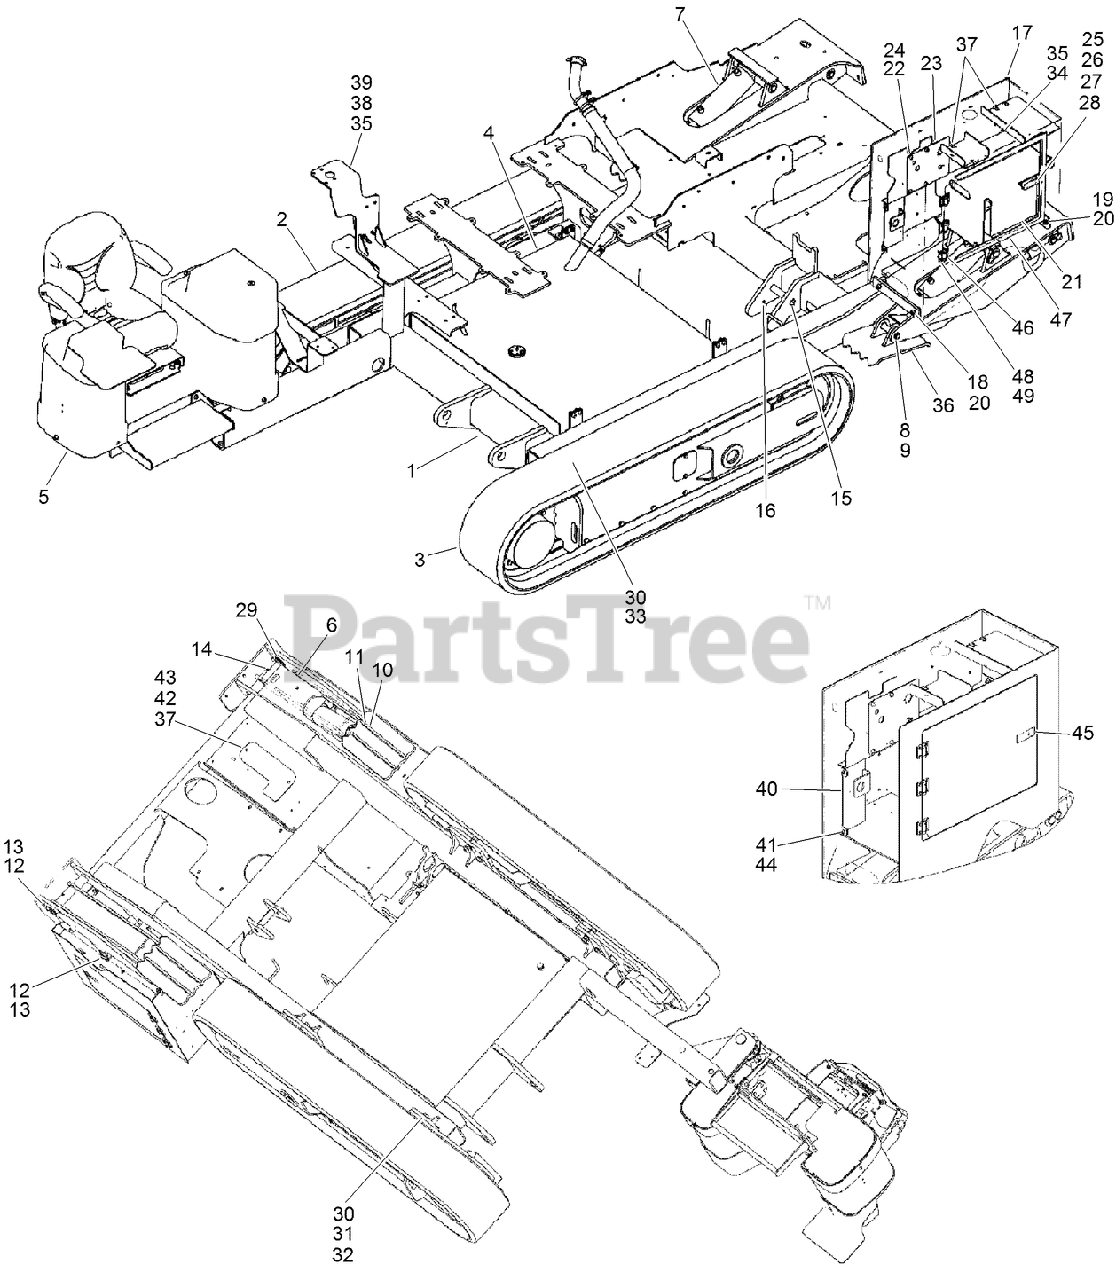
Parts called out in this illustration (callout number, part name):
1	WELDMENT - Chassis
2	ASSEMBLY - Track Drive, Right Hand
3	ASSEMBLY - Track Drive, Left Hand
4	ASSEMBLY - Fuel Tank
5	ASSEMBLY - Operators Console
6	WELDMENT - Stabilizer Assembly
7	HYD CYLINDER ASM
8	PIN (STABILIZER PAD END)
9	RING-RETAINING
10	PIN-STABILIZER (CYLINDER ROD END)
11	RING-RETAINING
12	PIN-W/FLAG
13	SCREW-HHF
14	FITTING-Lube 1/4-28 Tpr SAE-LT .54 Long
15	PIN-DIPPER CYLINDER TO BOOM
16	SCREW, METRIC FLANGE w/BODY-M12 x 30
17	ASSEMBLY - Console
18	SCREW-HHF
19	SCREW-HH
20	NUT-FLANGE, NYLOCK
21	PLATE - Cover
23	PLATE - Rear Controls Panel
24	SCREW, METRIC FLANGE w/BODY - M8 x 20
25	ANGLE-HOLDDOWN, BATTERY
26	PLATE-Battery Hold Down
27	BOLT-HOLDDOWN, BATTERY
28	NUT-Serr Flg 3/8-16 UNC GR5 ZND
29	WASHER-HARDENED
30	WASHER-FLAT
31	BOLT-hex, 3/4 NC x 3 inch, grade 8
32	NUT-Prev Trq 3/4 GRC CAD Direct
34	SCREW-HH
35	NUT-TORQUE, PREVAILING
36	WELDMENT - Stabilizer Foot
38	ASSEMBLY - Filter Mount
39	SCREW, METRIC FLANGE w/BODY - M8 x 35
40	PLATE - Corner
41	SCREW-HHF
42	COVER - 5 Section Valve
43	SCREW, METRIC FLANGE w/BODY-M6 x 25
44	NUT, METRIC FLANGE PREVAILING - M6 Zinc
45	LATCH-TRIGGER, RAISED (W/LOCK)
47	PLATE - Door
48	SCREW - PHd Type 1 #10 - 24 x 0.75 CST ZND
49	NUT-#10-24 KEPS
